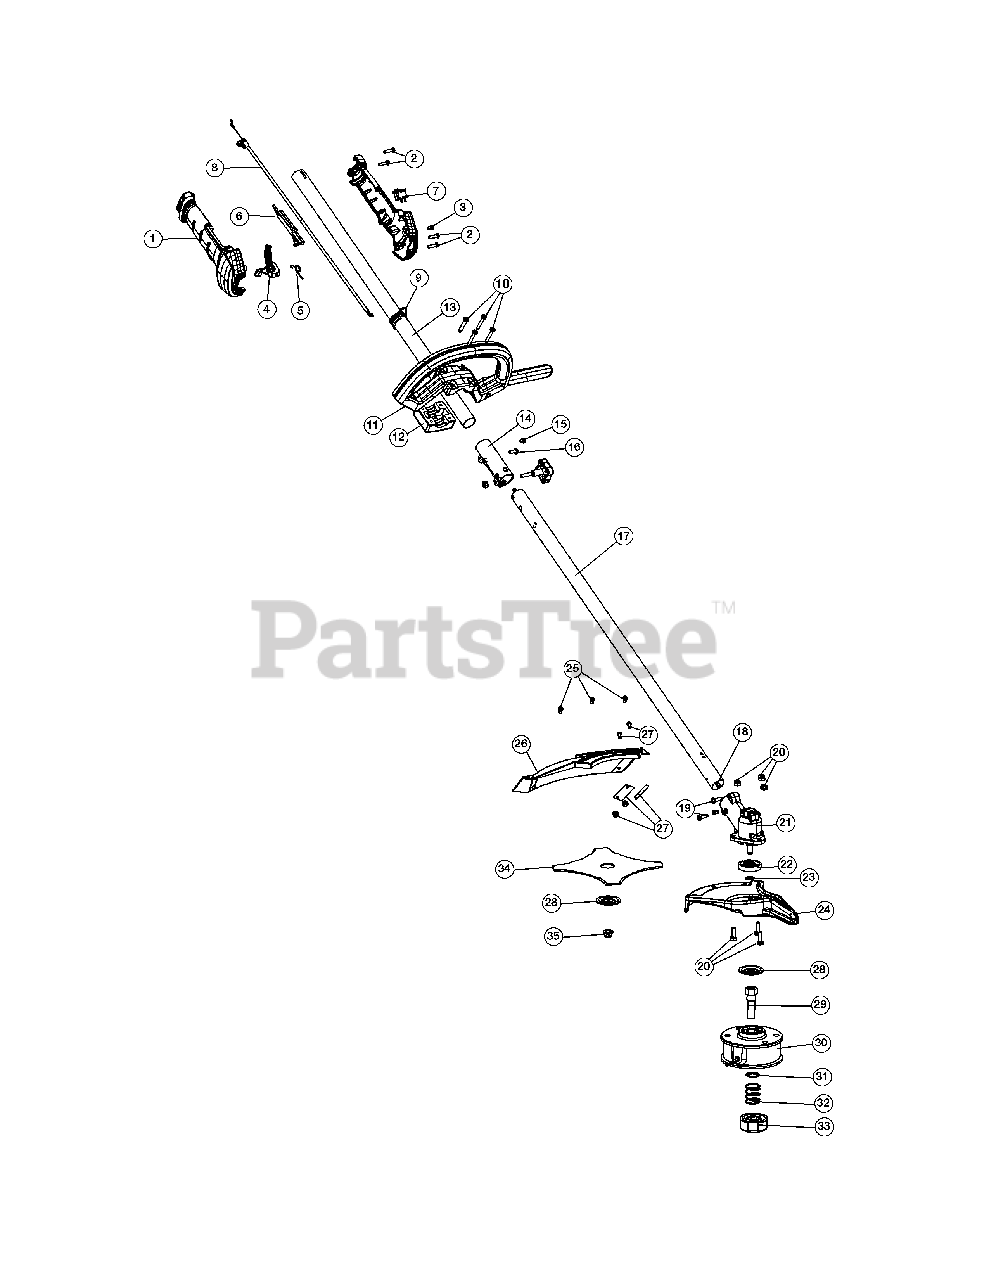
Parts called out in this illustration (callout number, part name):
1	Throttle Grip Assembly
3	Anti-Rotation Screw
4	Throttle Trigger
5	Throttle Trigger Spring
6	Lockout
8	Throttle Cable
9	Harness Clip
11	D-Handle
12	D-Handle Base
13	Upper Drive Shaft Assembly
14	Split Boom Coupler Assembly
17	Lower Drive Shaft Assembly
18	Lower Flex Shaft
19	Gearbox Mounting Hardware
20	Shield Mounting Hardware
21	Gearbox Assembly
22	Blade Driver
24	Blade Shield/Shield Mount
25	Shield Mounting Screw
26	Shield Assembly
27	Blade Assembly
28	Retaining Washer
29	Spool Shaft
30	Outer Spool Assembly
31	Retainer
33	Bump Head Knob Assembly
34	4-Tooth Blade
